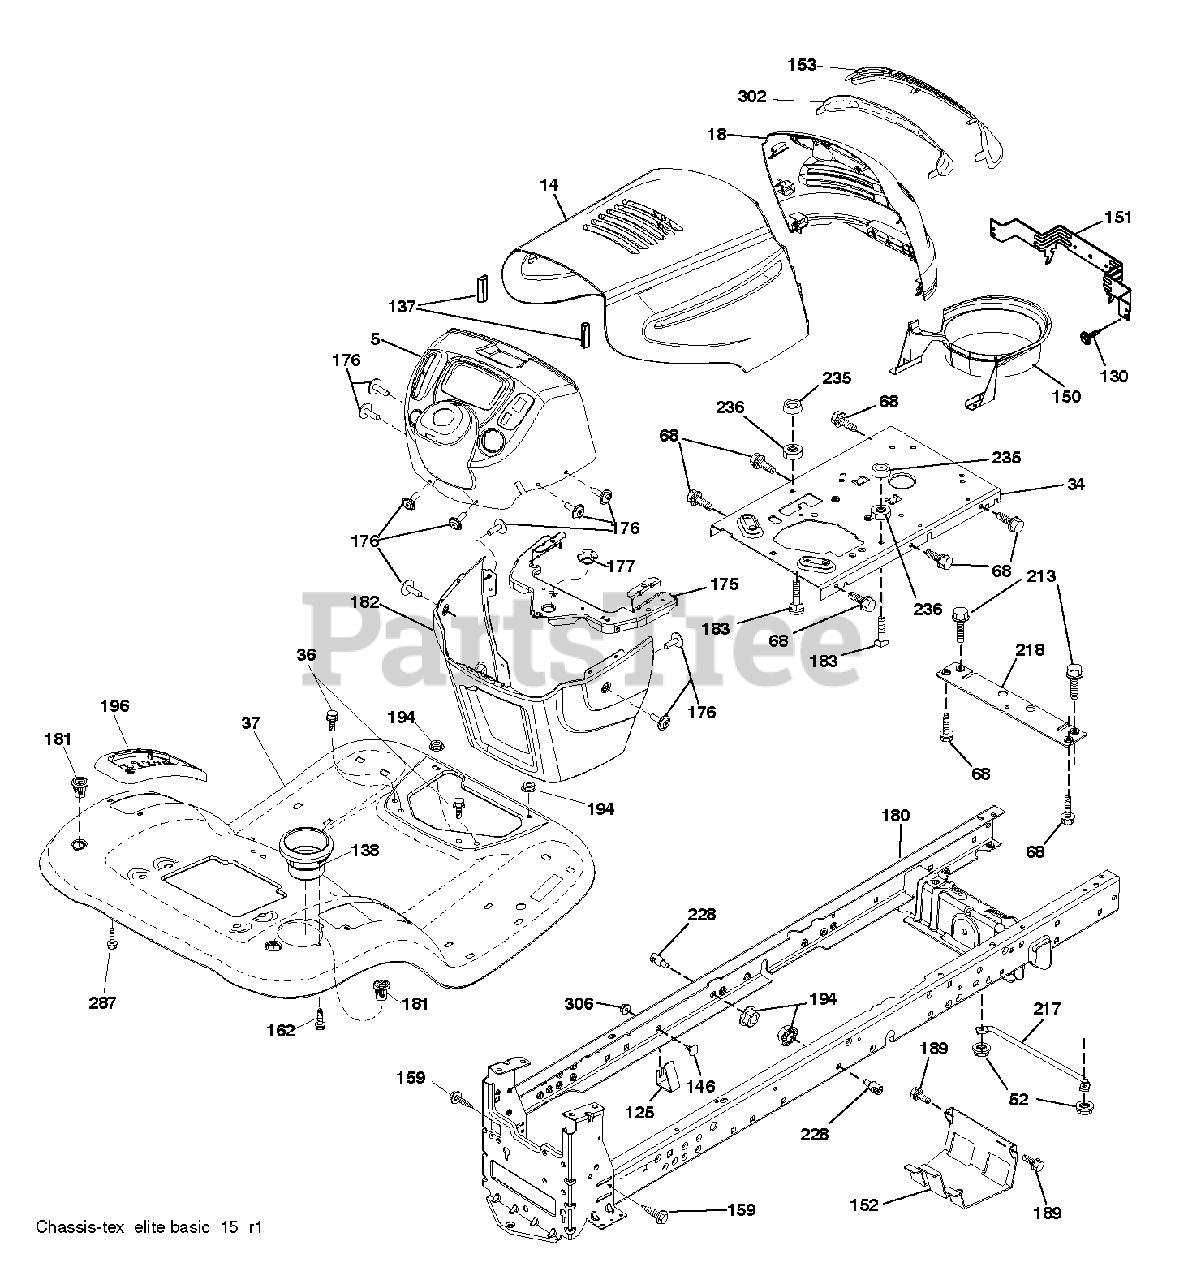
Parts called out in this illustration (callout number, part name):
5	DASH.P/L.TEX.CBL.CL.N/CHK.BLAC
14	HOOD.STL.ELITE.TOPLVRS.428
18	GRILLE.ELITE.BASIC.LT.BLACK
34	PLATE.ENGINE.WELDED.CHASSIS
36	SCREW 5/16"
37	FENDER.TLT.FS.W/CPH.428
52	LOCKNUT
68	SCREW LT
125	CLIP.FUEL.LINE
130	SCREW.#10 X 0.750.BOS (2 2)
137	BUMPER.HOOD.LARGE.1.75"
138	CUPHOLDER.TL.TEX.BLACK
146	BOLT.RDHD.SHT.SQNK.3/8-16X5/8
150	DUCT.INTAKE.AIR.KAW
151	BRACKET PIVOT
152	SHIELD.BROWNING.W/TEX
153	LENS.GRILLE.BASIC.BAR.LT.CLR
159	SCREW, 3/8-16X3/4
162	SCREW.HI-LO.CONSOLE
175	CROSSMEMBER.LT
176	SCREW.#10-24X5/8.RN.QU
177	BUSHING STEERING
180	CHASSIS
181	FEND/FTRST.PCH.CPH.NFW
182	DASH.LOWER.LT.CCS
183	BOLT.5/16-18X1-1/4 FULL THD
189	SCREW
194	NUT LOCK HEX FLANGE 5/16-18
213	BOLT
217	ROD.PIVOT.HOOD
218	X-PIECE.HOOD.STOP.NON/
228	STUD.FASTNER.W/ANTI-ROTATE
235	SPACER FENDER
236	NUT.CENTERLOCK.5/16-
287	SCREW 1/4X20
302	INSERT.LENS.REFLECTIVE.LEFT
306	NUT LOCK FLG 3/8-16 UNC
